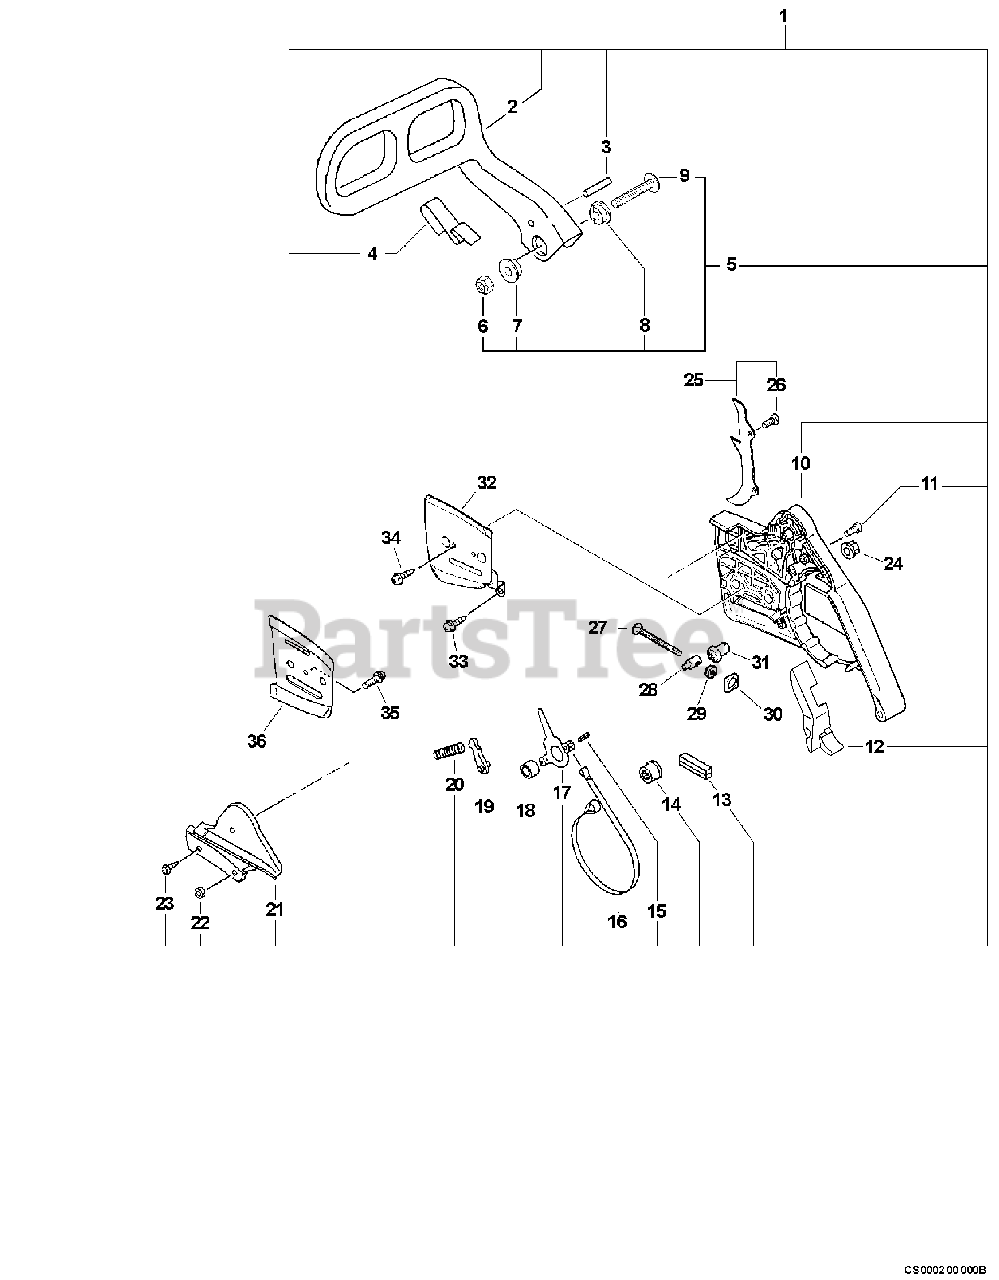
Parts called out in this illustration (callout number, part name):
1	CHAIN BRAKE ASSY
2	LEVER, BRAKE
3	PIN - 3.5X26
4	SPRING, RETURN
5	MOUNTING KIT
8	COLLAR - 5
9	SCREW - 5X35
10	SPROCKET GUARD KIT
11	SCREW - 3X18
12	CUSHION
14	ADJUSTER, BRAKE BAND
15	PIN - SPRING -- 4X8
16	BAND, BRAKE
17	LEVER, BRAKE
18	SPACER - 8
19	STOPPER, BRAKE
20	SPRING, BRAKE
21	COVER, BRAKE
23	SCREW - 4X12
24	NUT - FLANGE
25	SPIKE KIT
26	SCREW - 5X12
27	SCREW, TENSIONER
28	TENSIONER, CHAIN
29	GEAR - BEVEL
30	COLLAR - 8
31	GEAR - PINION
32	PLATE, GUIDE - OUTER
33	SCREW - 4X10
34	SCREW - 3X6
35	SCREW - 4X8
36	PLATE, GUIDE - INNER
